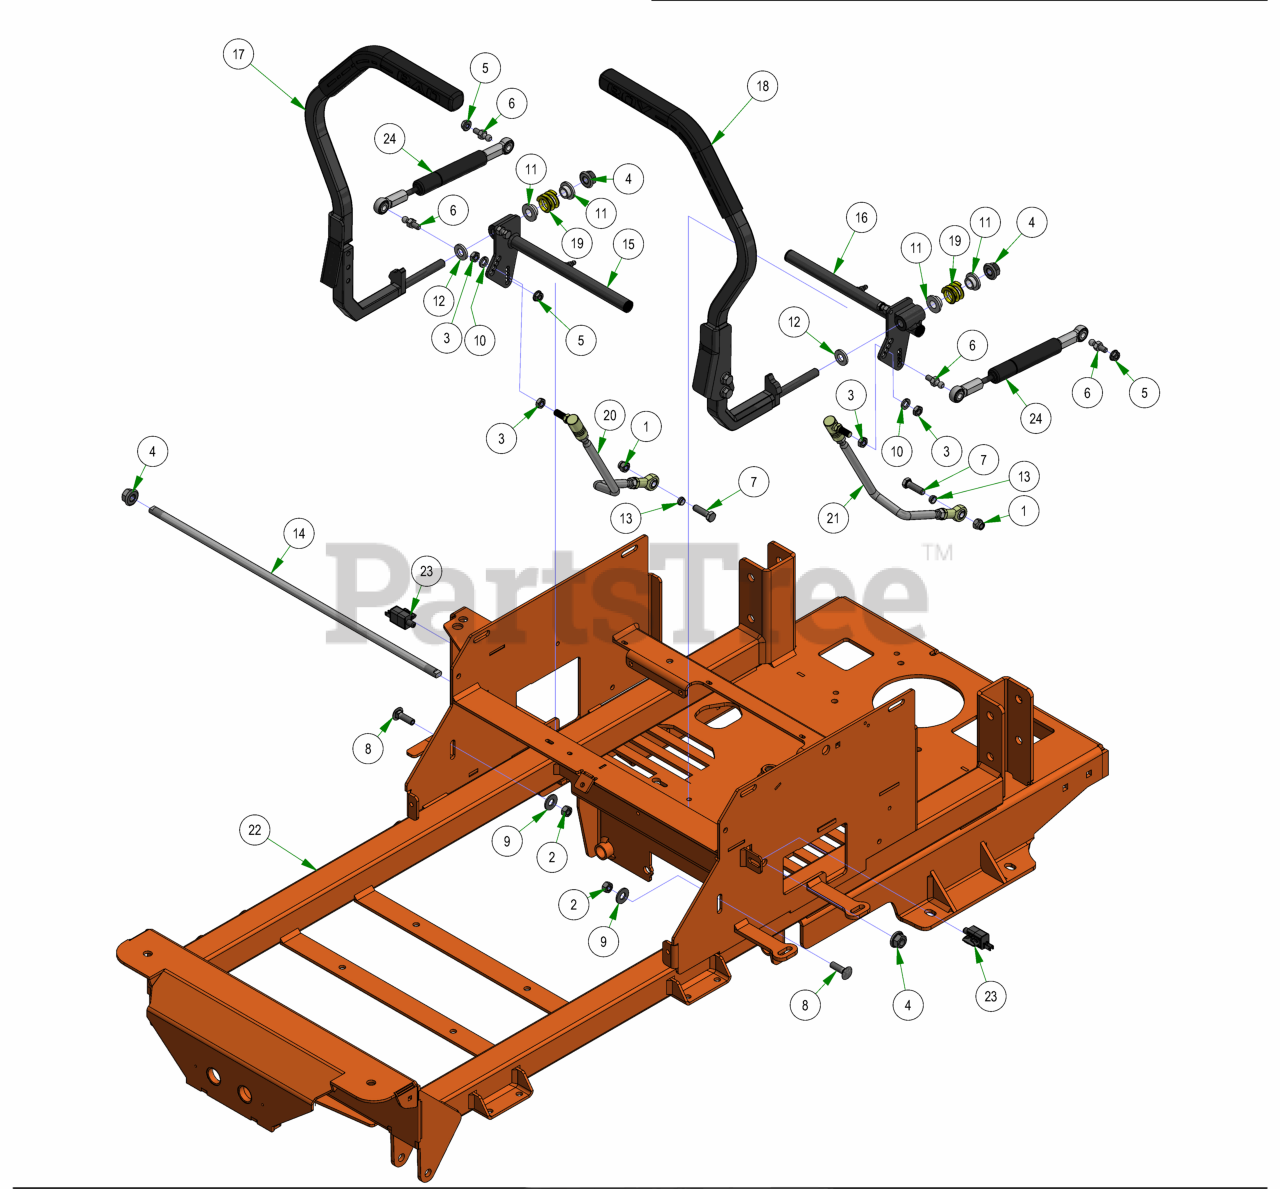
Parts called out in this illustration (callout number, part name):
1	3/8-16 NYLON INSERT LOCKNUT ZINC
2	3/8-16 HEX NUT ZINC
3	3/8-24 HEX NUT ZINC YELLOW
4	1/2-13 NYLON INSERT FLANGE LOCKNUT ZINC
5	5/16-18 HEX SERRATED FLANGE NUT HARD/ZINC
6	10mm Damper Ball Stud-Steering
7	3/8-16 X 1-1/4 HEX CAP SCREW (GR.5) ZINC
8	3/8-16 X 1-1/4 CARRIAGE BOLT ZINC
9	3/8 FLAT WASHER USS (1" OD) ZINC
10	3/8 SPLIT LOCKWASHER ZINC
11	.525 ID SHOULDER WASHER NYLON
12	.505 ID X 1.000 OD X .125 THICK FLAT WASHER NYLON
13	Drive Arm Transaxle Spacer
14	2021 Maverick Steering Actuator Rod
15	2021 Maverick Drive Arm Actuator RH Assembly
16	2021 Maverick Drive Arm Actuator LH Assembly
17	Small Mower Square Drive Arm RH Assembly
18	Small Mower Square Drive Arm LH Assembly
19	Drive Lever Spring
20	Push Rod-Right
21	Push Rod-Left
22	2025 Maverick Frame
23	Rail Mount Safety Switch
24	Steering Damper
